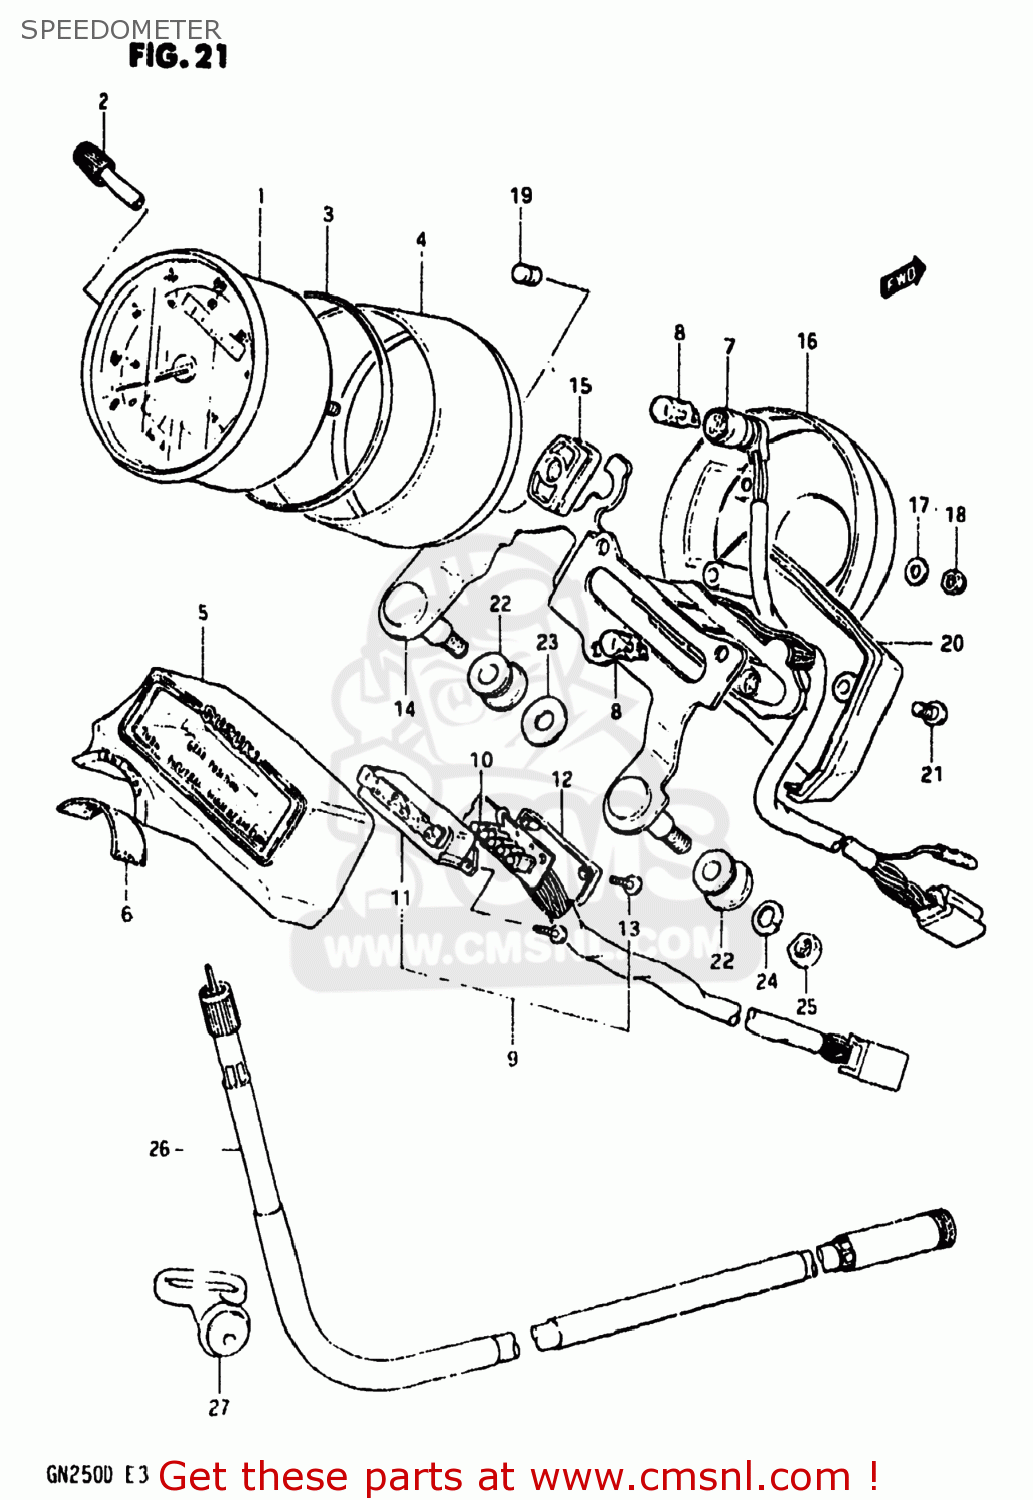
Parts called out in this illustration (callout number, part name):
1	SPEEDOMETER ASSEMBLY
2	KNOB
3	CUSHION
4	COVER,SPEEDOMETER
5	CASE,PILOT BULB
6	SEAL,IGNITION SWITCH
7	SOCKET,SPEEDOMETER
8	BULB(12V3.4W,T10)
9	INDICATOR ASSY,GEAR POSITION
10	BULB(14V1.12W)
11	CASE,GEAR INDICATOR
12	COVER,LWR
13	SCREW,GEAR INDICATOR
14	BRACKET,SPEEDOMETER
15	CUSHION,METER
16	ORNAMENT,SPEEDOMETER
17	WASHER
18	NUT
19	CUSHION
20	COVER,PILOT BOX,UNDER
21	SCREW 4X10
22	CUSHION,METER BRACKET
23	WASHER (8.5X29X1.6)
24	LOCK WASHER
25	NUT
26	CABLE ASSY,SPEEDOMETER
27	GUIDE,CABLE
